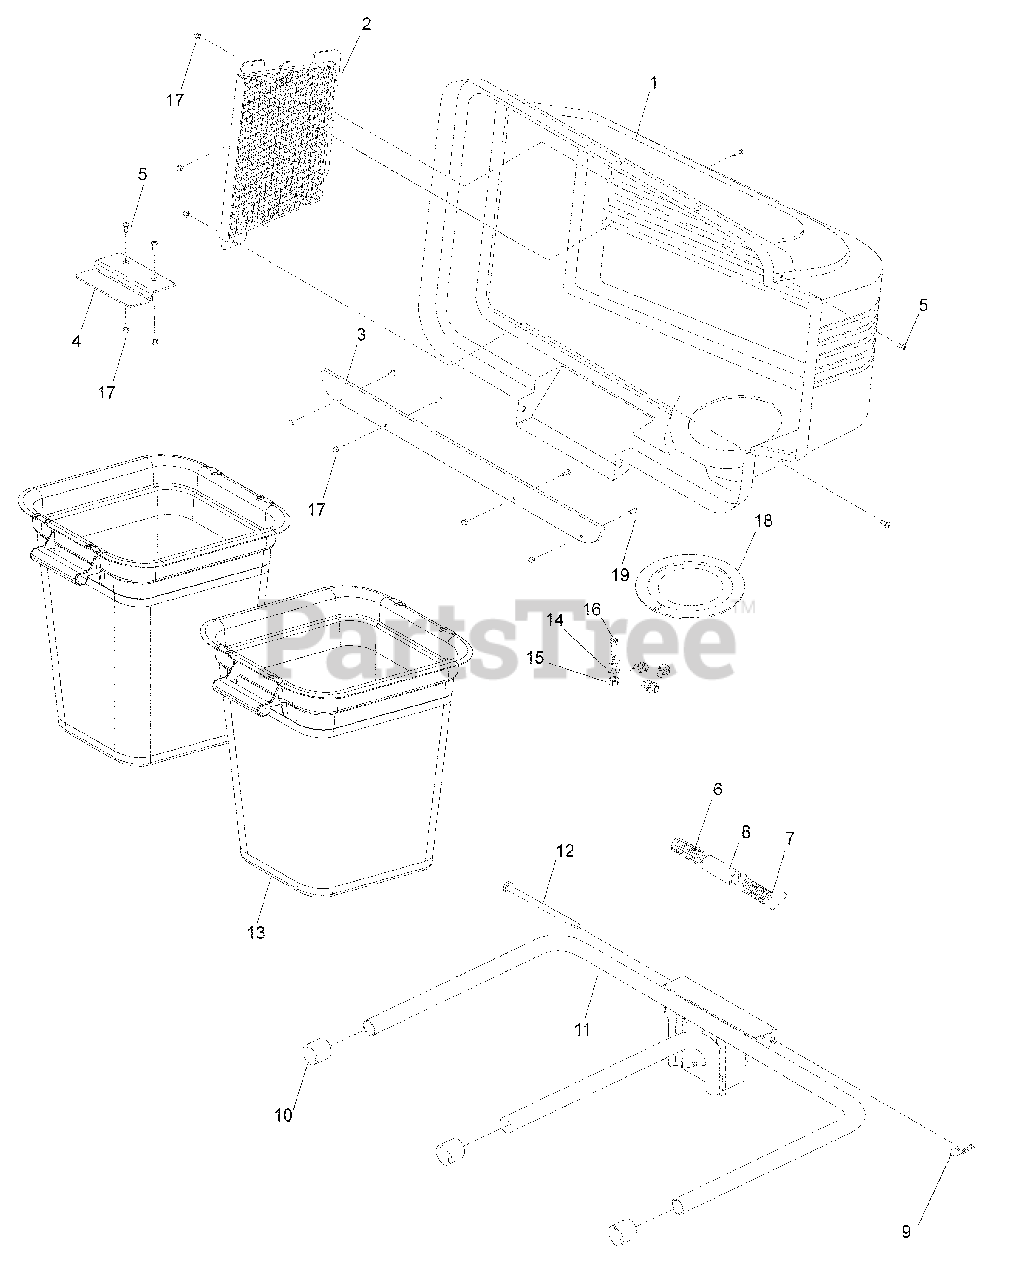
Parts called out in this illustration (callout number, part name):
1	COVER ASSM, COMPLETE
2	SCREEN, COVER
3	STRIP, REINFORCEMENT
4	LATCH HANDLE, COVER
5	SCREW #10-24 x 5/8
6	SPRING, COVER, LH
7	SPRING, COVER RH
8	SPACER, COVER
9	SPRING, RETAINER
10	CAP, TUBING END
11	BAGGER, FRAME
12	PIN, HINGE
13	CONTAINER, SOFT BAG
14	WASHER #10 FLAT
15	NUT #10-24 HEX NYLOC
16	HMS #10-24 x ¾
17	NUT #10-24 ACORN
19	SCREW #10-24 x ½
